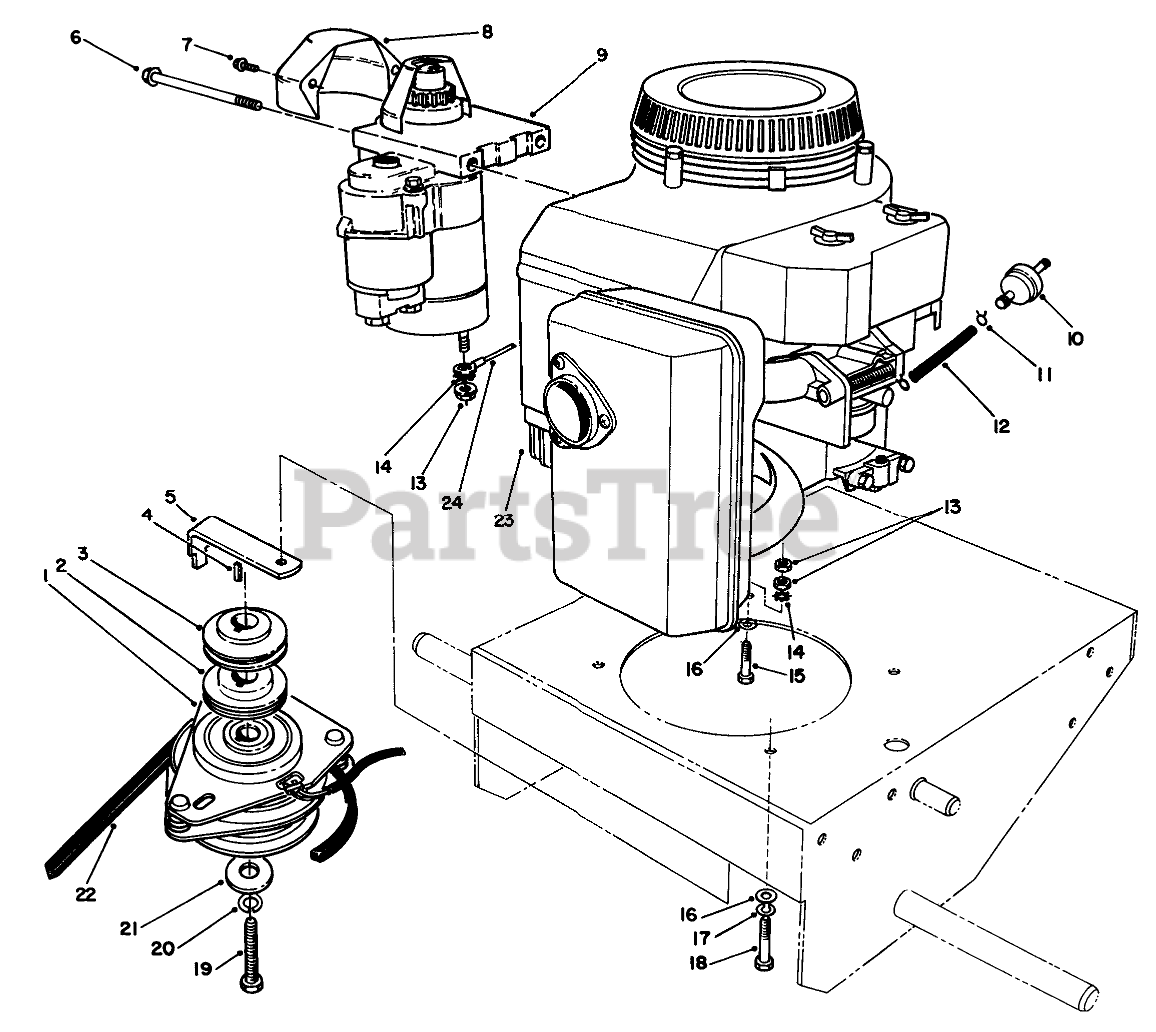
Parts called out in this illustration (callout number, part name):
1	CLUTCH/BRAKE
2	SHEAVE-LOWER HALF
3	SHEAVE-UPPER HALF
4	KEY-SQUARE
5	Retainer-Clutch
6	Screw-Hex. Hd. Cap
7	Screw-Hex. Hd. Cap
8	Cover
9	Motor-Starter/Alternator
10	FILTER-FUEL
11	CLAMP-HOSE
12	HOSE-FUEL
13	NUT-JAM
14	WASHER-LOCK
15	SCREW (ENGINE, GROUND)
16	WASHER-PLAIN
17	WASHER-LOCK
18	SCREW-HH
19	SCREW-CLUTCH
20	WASHER-LOCK
21	WASHER-CLUTCH
22	V-BELT, DRIVE
24	WIRE ASM
